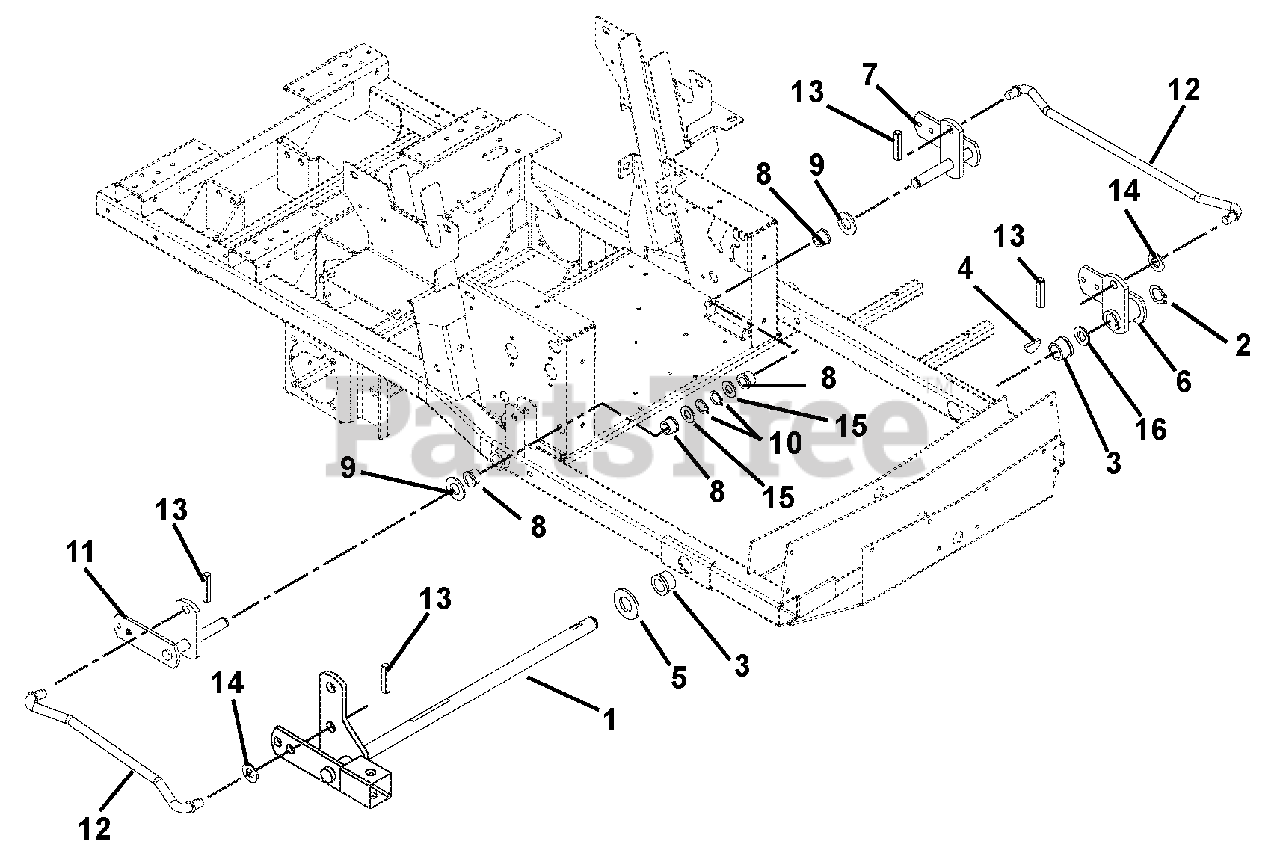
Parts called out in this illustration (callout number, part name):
1	Lift, Mower
2	Ring, Retaining External 1.00 x .078
3	Bushing, Flange Nylon 1.02 x 1.385 x .75 x 1.75
4	Key, Woodruff .25 x 1.00
5	Washer, Flat Steel 1.063 x 2.00 x .134
6	Weldment, Lift Arm-Front
7	Weldment, Rear Lift Arm-Left Hand
8	Bushing, Flange Nylon .762 x 1.0 x .58 x 1.48
9	Washer, Hardened Steel .758 x 1.23 x .031
10	Ring-Retaining-External .689 x .077
11	Weldment, Rear Lift Arm- Right Hand
12	Rod, Lift Assist 19.35"
13	Pin, Roll .25 x 1.25 Stainless Steel
14	Washer, Flat Steel .630 x 1.25 x .062
15	Washer, Flat Steel .755 x 1.25 x .125
16	Washer, Hardened Thrust 1.00 x 1.55 x .03
